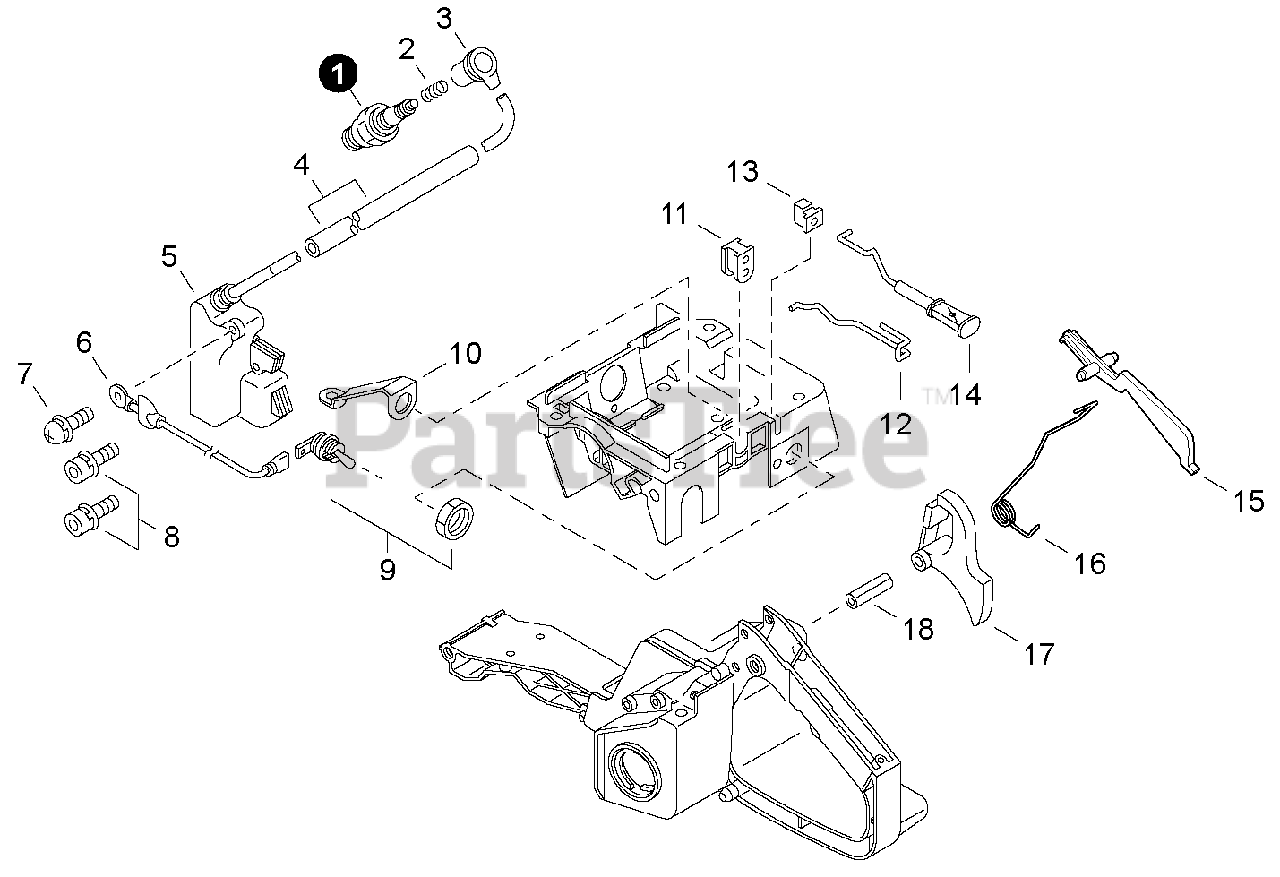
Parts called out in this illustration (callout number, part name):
1	SPARK PLUG -- BPM-7A
2	TERMINAL, SPARK PLUG CAP
3	CAP, SPARK PLUG
5	COIL, IGNITION
6	LEAD - GROUND
7	SCREW - 4X8
8	SCREW - 4X20
9	IGNITION SWITCH ASSY
10	TERMINAL - GROUND
12	ROD, THROTTLE
14	ROD, CHOKE
15	LEVER, TRIGGER LOCKOUT
16	SPRING, TRIGGER
17	TRIGGER, THROTTLE
18	PIN - SPRING -- 5X25
